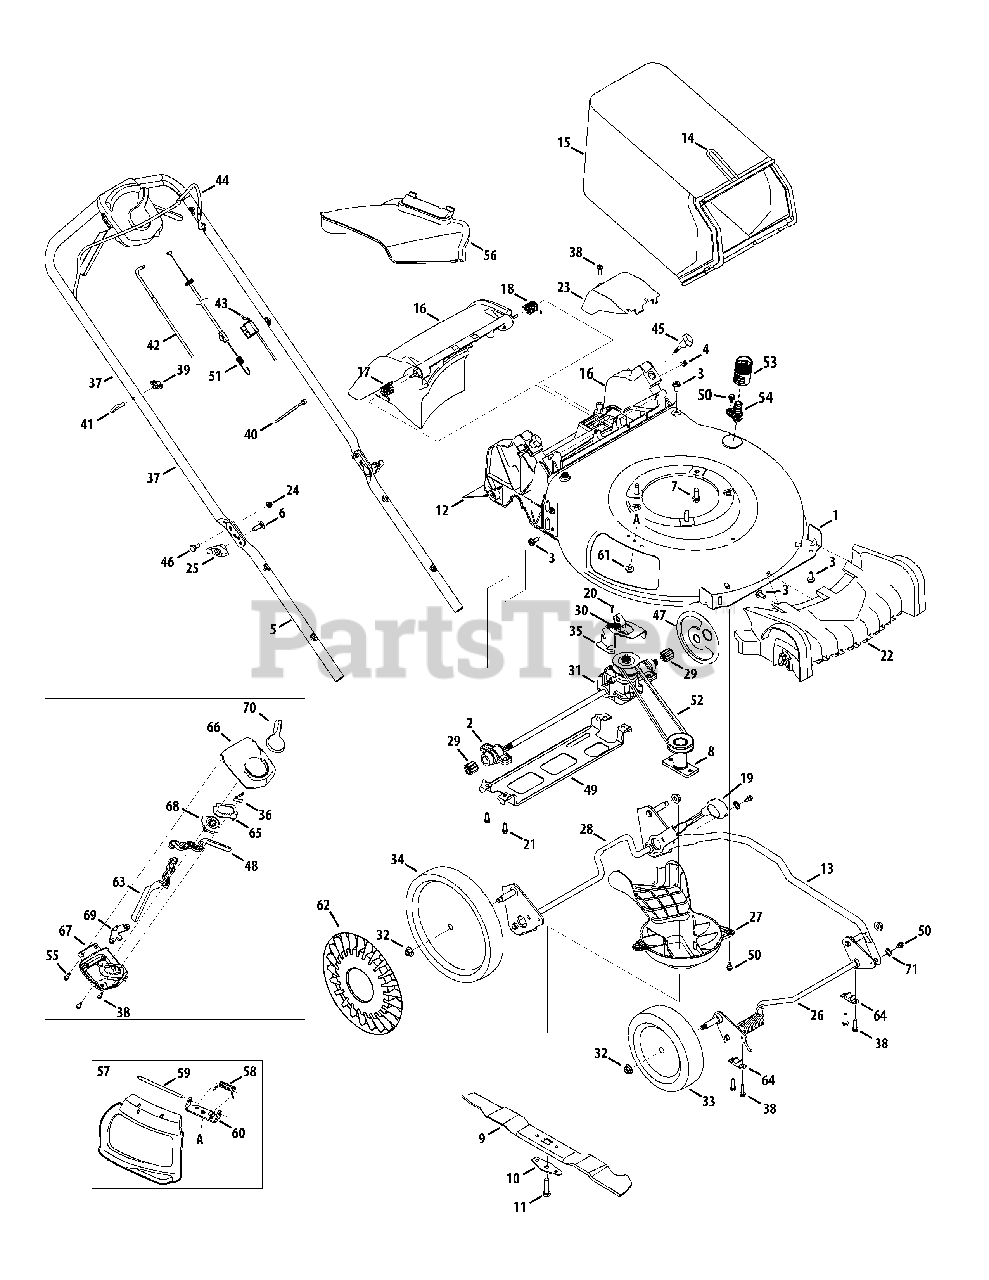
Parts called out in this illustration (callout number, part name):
1	21" Deck Ass’y
2	Bearing Assembly
3	Hex Hd. Cap Screw 5/16-14 x .75
4	Sq. Nut 1/4-20
5	Lower Handle
6	Carriage Bolt 5/16-18
7	Hex Wash HD Tap Scr 3/8-16 x .88
8	Blade Adapter
9	21" Mulching Blade
10	Blade Bell Support
11	Hex Bolt 3/8-24 x 1.5" Lg. (Gr 8)
12	Trailing Shield 4.54 x 17.37
14	Catcher Frame
15	Grasscatcher Bag
16	Rear Baffle Ass'y (Incl. door)
17	RH Torsion Spring
18	LH Torsion Spring
19	Knob (Black)
20	Sems TT Screw 1/4-20 x .50
21	Screw 1/4-15 x 1.25
22	Front Axle Cover
23	Transmission Cover
24	Flanged Lock Nut 1/4-20 Gr. F Ny lon
25	Wing Knob-Black
26	Front Axle Ass'y
27	Engine Baffle
28	Rear Axle Ass'y
29	Spur Gear 9T
30	Extension Spring 2.405
31	Transmission Ass'y
32	Flange Locknut 3/8-16 Gr. F Ny lon
33	Front Wheel
34	Rear Wheel
35	Transmission Bracket
36	Spring
37	Upper Handle - Black
38	Screw, 1/4-15 x .750
39	Knob 1/4-20
40	Cable Tie
41	Rope Guide Bolt
42	Drive Cable
43	Control Cable (Honda)
44	Blade Control (Black)
45	Knob 1/4-20 x 1.73 Black
46	Shoulder Screw .375 x .126 x 1/4-20
47	Dust Cover
48	Control Lever LH
49	Rear Support Bracket
50	Shoulder Screw 1/4-20 x .50
51	Speed Adjustment Cable
52	V Belt
53	Water Nozzle Adapter
54	Deck Water Nozzle
55	Shoulder Screw 1/4-15 x .970
56	Chute De flector
57	Mulching Plug Ass'y (Incl. ref. no. 58-60)
58	Torsion Spring
59	Hinge Pin
60	Chute Deflector Bracket
61	Screw 1/4-20 x .50
62	Hub Cap
63	Control Le ver RH
64	Bushing .505 Dia. x .62
65	Cable Ad just Plate
66	Upper Housing
67	Lower Housing
68	Speed Adjust Actuator
69	Drive Cable Actuator
70	Speed Select Lever
71	Wave Washer
